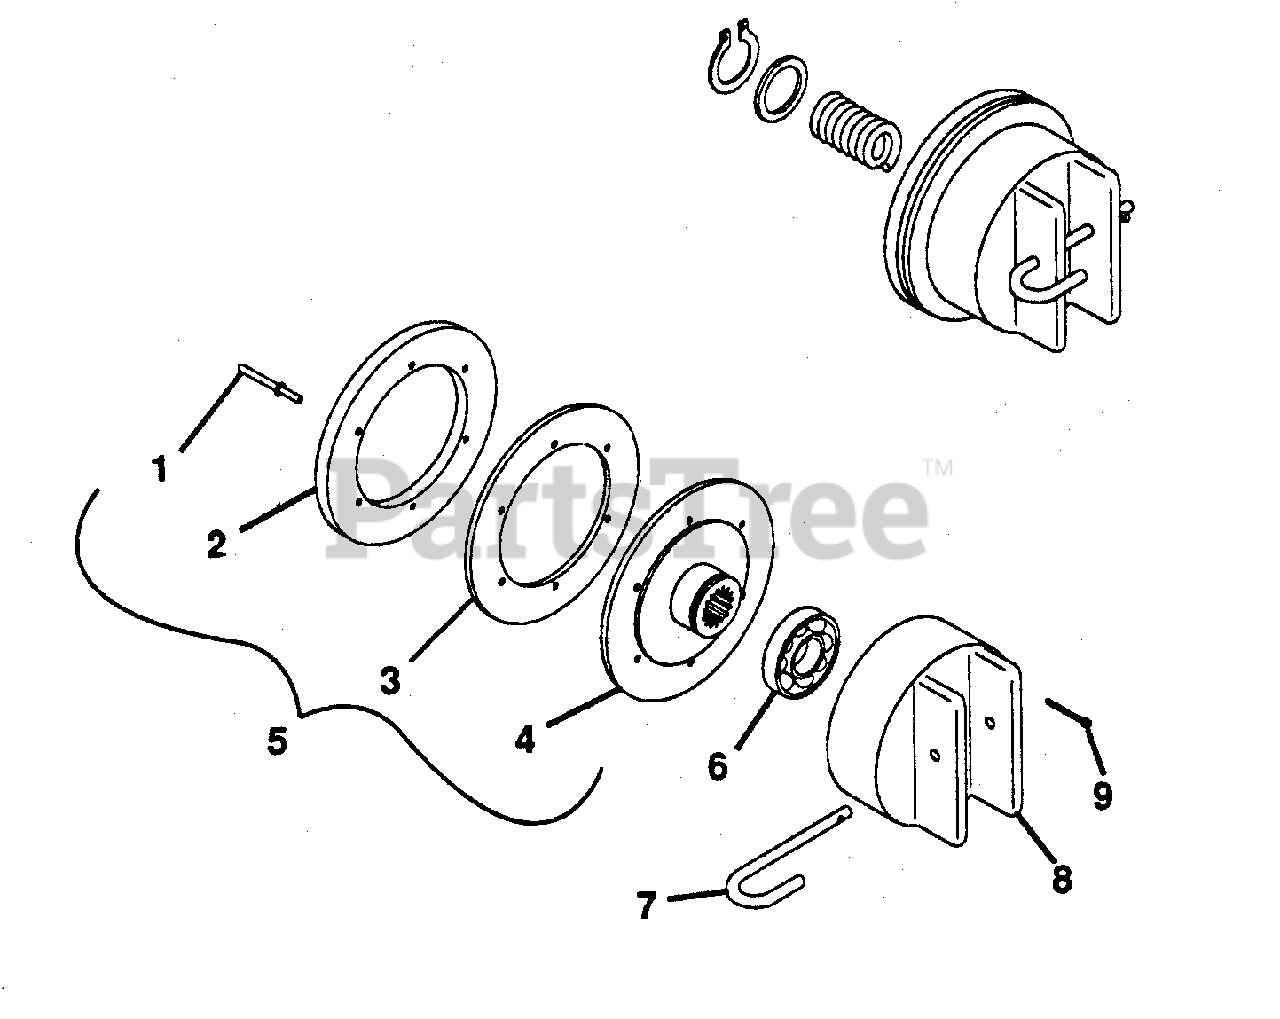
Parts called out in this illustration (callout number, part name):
1	RIVET, STEEL(BAG OF 50)
2	LINING, CLUTCH
3	RING, CLUTCH
4	DISC, CLUTCH
5	ASSEMBLY, CLUTCH AND RING
6	BEARING, BALL 1.574X3.149X.708
7	PIN, CLUTCH SPRING
8	TRUNNION, FWD-REV CLUTCH
9	PIN, COTTER .06X.75
